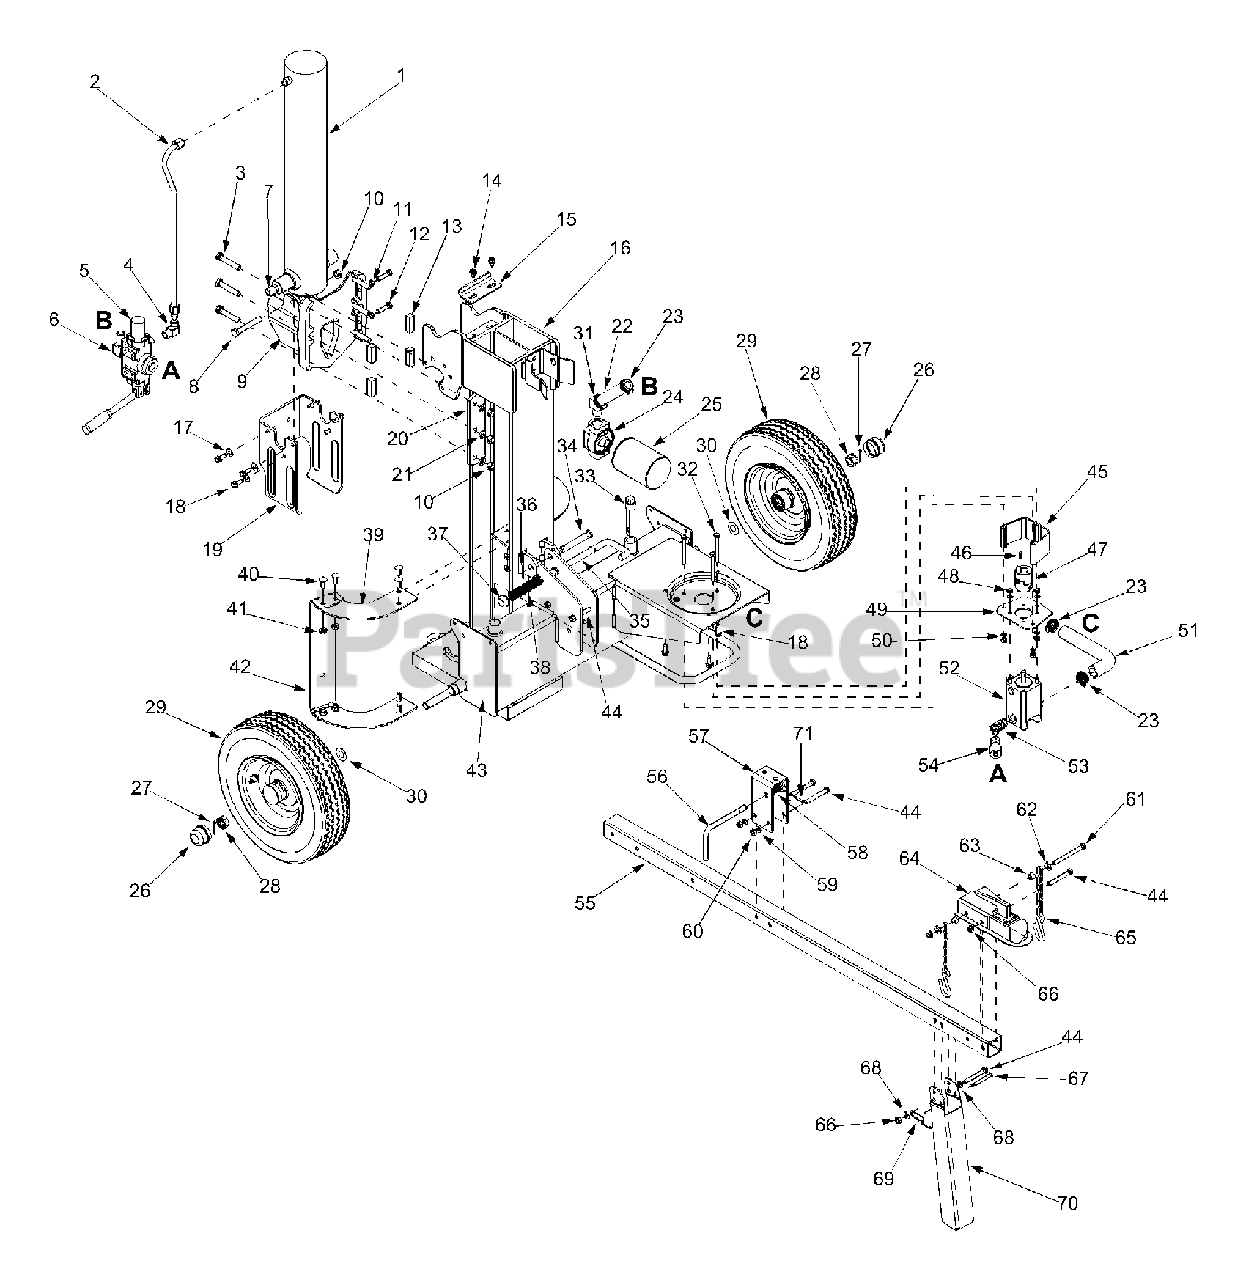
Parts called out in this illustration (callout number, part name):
1	Hydraulic Cylinder
2	Hydraulic Tube
3	Hex Cap Screw 1/2-20 x 2.75
4	90 Degree Solid Adapter
6	Return Elbow
7	Nipple Pipe 1/2-14
8	Hex Cap Screw 1/2-20 x 3.50
9	Wedge Assembly
10	Lock Nut 1/2-20
11	Hex Jam Nut 3/8-24
12	Hex Cap Screw 3/8-24 x 1.5
14	Hex Washer Screw 5/16-18 x .625
17	Flat Washer .406 ID x .875 OD
18	Hex Washer Screw 3/8-16 x 1.0
21	Lock Washer 1/2
22	Return Hose 3/4" ID x 44" Lg.
23	Hose Clamp 5/8"
24	Filter Housing
25	Oil Filter
26	Hub Cap
27	Cotter Pin
28	Slotted Nut 3/4-16
29	Wheel Assembly
30	Flat Washer .760 ID x .500 OD
31	Adapter 3/4-14
32	Hex Screw 5/16-24 x 3.25
33	Vented Dipstick
34	Clevis Pin
35	Lock Rod
36	Cotter Pin
37	Push Cap
38	Compression Spring
41	Flanged Lock Nut 3/8-16
43	Frame Assembly
44	Hex Bolt 3/8-16 x 3"
45	Coupling Shield
46	Square Key 3/16" x .75
47	Flexible Coupling .750 x .500
47	Flexible Coupling .875 x .500
47	Flexible Coupling .875 x .437
48	Hex Nut 5/16-24
50	Lock Washer 5/16" ID
52	Gear Pump (11 gpm)
52	Pump Kit
52	Gear Pump (9.5 gpm)
53	45 Degree Elbow
54	High Pressure Hydraulic Hose
56	Latch Rod
58	Spring Compression
59	L-Washer 3/8"
60	Hex Nut 3/8-16
61	Hex Cap Screw 3/8-16 x 4.25
62	Flat Washer .385 ID x .870 OD
63	Spacer .375 ID x .625 OD
64	Coupling Hitch
65	Chain
66	Hex Lock Nut 3/8-16
67	Clevis Pin
68	Flat Washer .375 ID x .738 OD
69	Spring Pin
